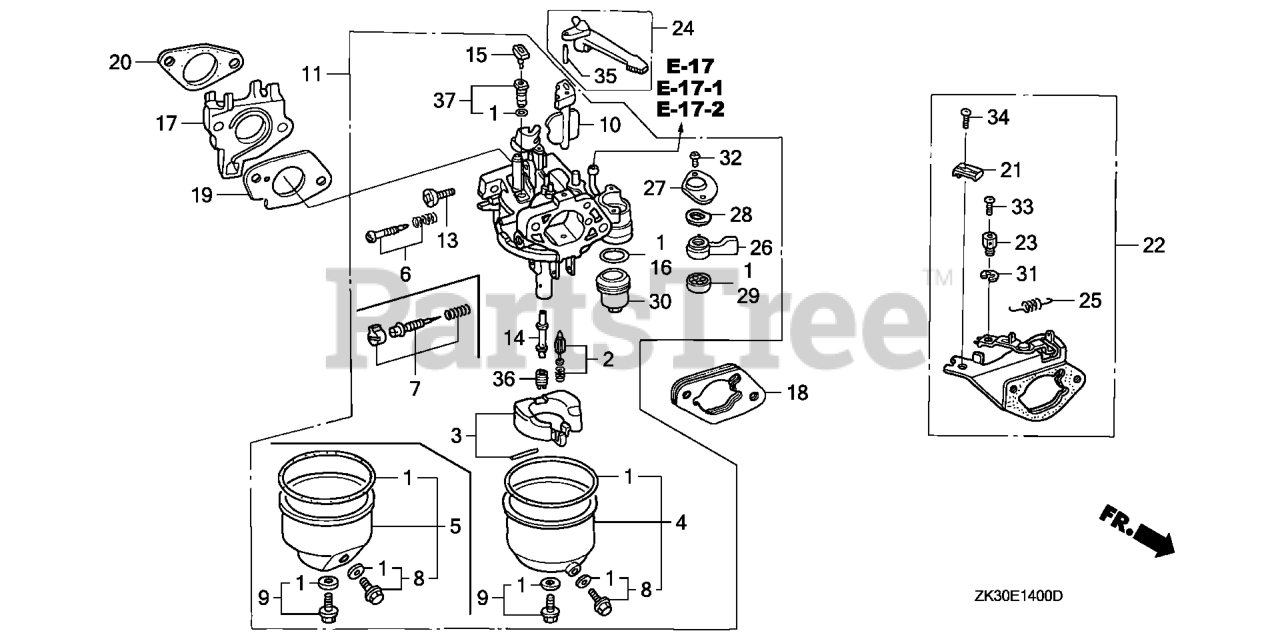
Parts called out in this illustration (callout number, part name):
1	GASKET SET (INCLUDE 16173-001-004) (INCLUDES 16173-001-004)
2	VALVE SET, FLOAT
3	FLOAT SET
4	CHAMBER SET, FLOAT
5	CHAMBER SET, FLOAT
7	SCREW SET (Honda Code 4219879). (CARBURETOR NO.)
8	SCREW SET, DRAIN (Honda Code 1672187). (CARBURETOR NO.)
9	SCREW SET B
9	SCREW SET
10	CHOKE SET
11	CARBURETOR ASSY. (BE80B B)
13	SCREW, THROTTLE STOP
14	NOZZLE, MAIN (CARBURETOR NO.)
15	COLLAR, SET
16	GASKET, FUEL STRAINER CUP
17	INSULATOR, CARBURETOR
18	SPACER, CARBURETOR
19	GASKET, CARBURETOR
20	GASKET, INSULATOR
24	LEVER, CHOKE (STD)
26	LEVER, VALVE
27	PLATE, LEVER SETTING (CARBURETOR NO.)
28	SPRING, PETCOCK LEVER (CARBURETOR NO.)
29	GASKET, VALVE
30	CUP, FUEL STRAINER
32	SCREW, PAN (3X6)
32	SCREW, PAN (3X8) (CARBURETOR NO.)
35	PIN, SPRING (2X12)
36	JET, MAIN (#92) (CARBURETOR NO.)
36	JET, MAIN (#88) Use up to Engine SN BE81B B.
36	JET, MAIN (#90) Use from Engine SN BE81B C.
36	JET, MAIN (#92)
37	JET SET, PILOT (#35)
